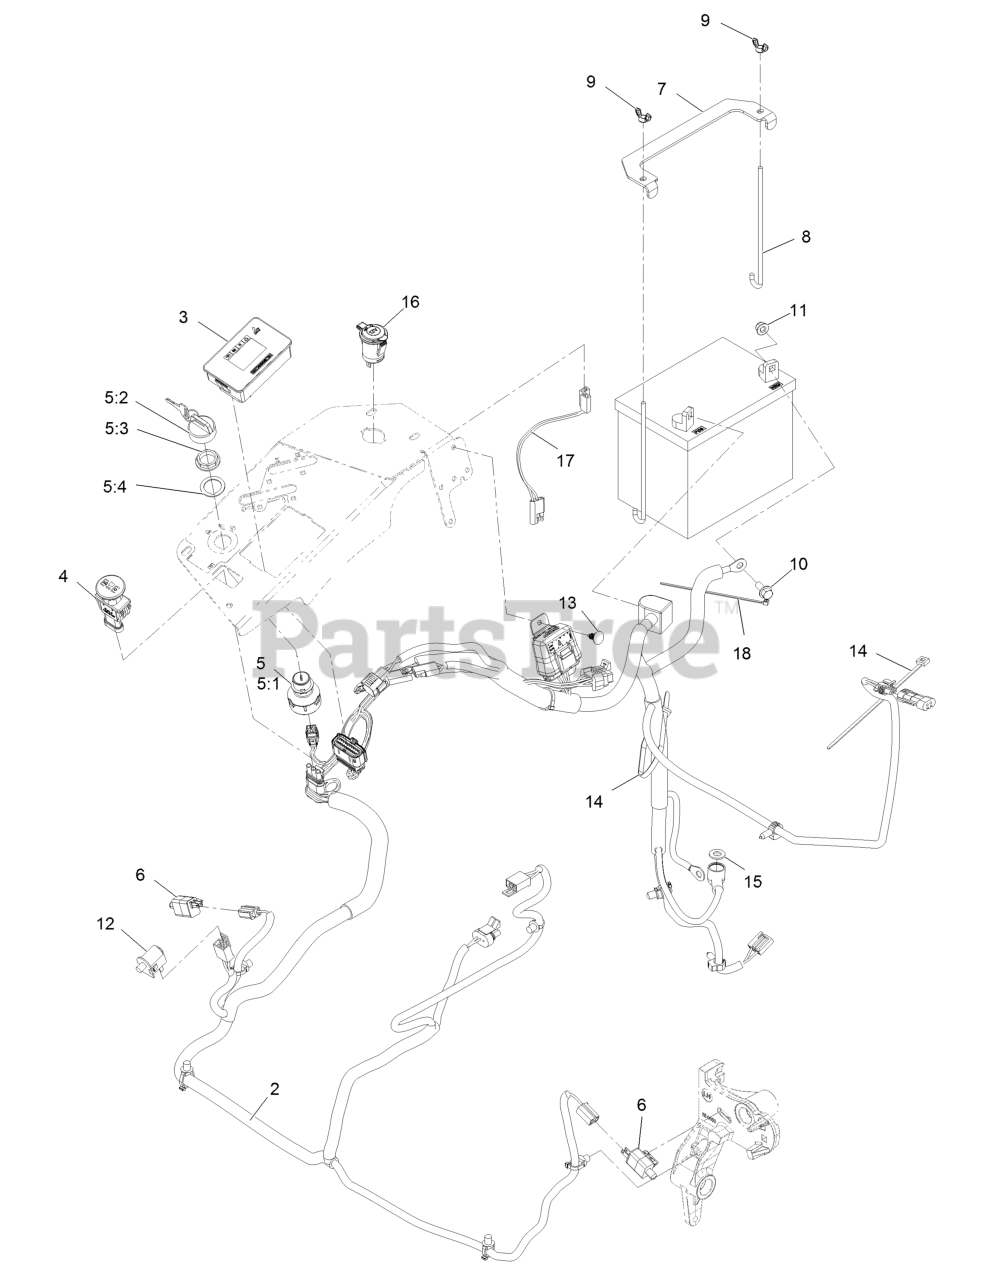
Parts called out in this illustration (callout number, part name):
2	Wire Harness ASM
3	Meter-Hour
4	Switch-PTO, Sealed
5	Ignition Switch ASM
5:1	Switch-Ignition
5:2	Nut-Mounting
5:3	Ignition Key Set
5:4	Washer-Backup
7	Strap-Tie Down, Battery
8	Bolt-Holddown
9	Wingnut-Nyloc 1/4-20
10	Screw-HH Flg 5/16-18 X 3/4
11	Nut-Nyloc 5/16-18 Flg
13	Plug-Plastic
14	Tie-Cable 7 15/16 (Large)
15	Washer-3/8 SAE
16	Port-Power, 12V
17	Harness-Receptacle, 12V
18	Tie-Cable 5 1/2 (Small)
